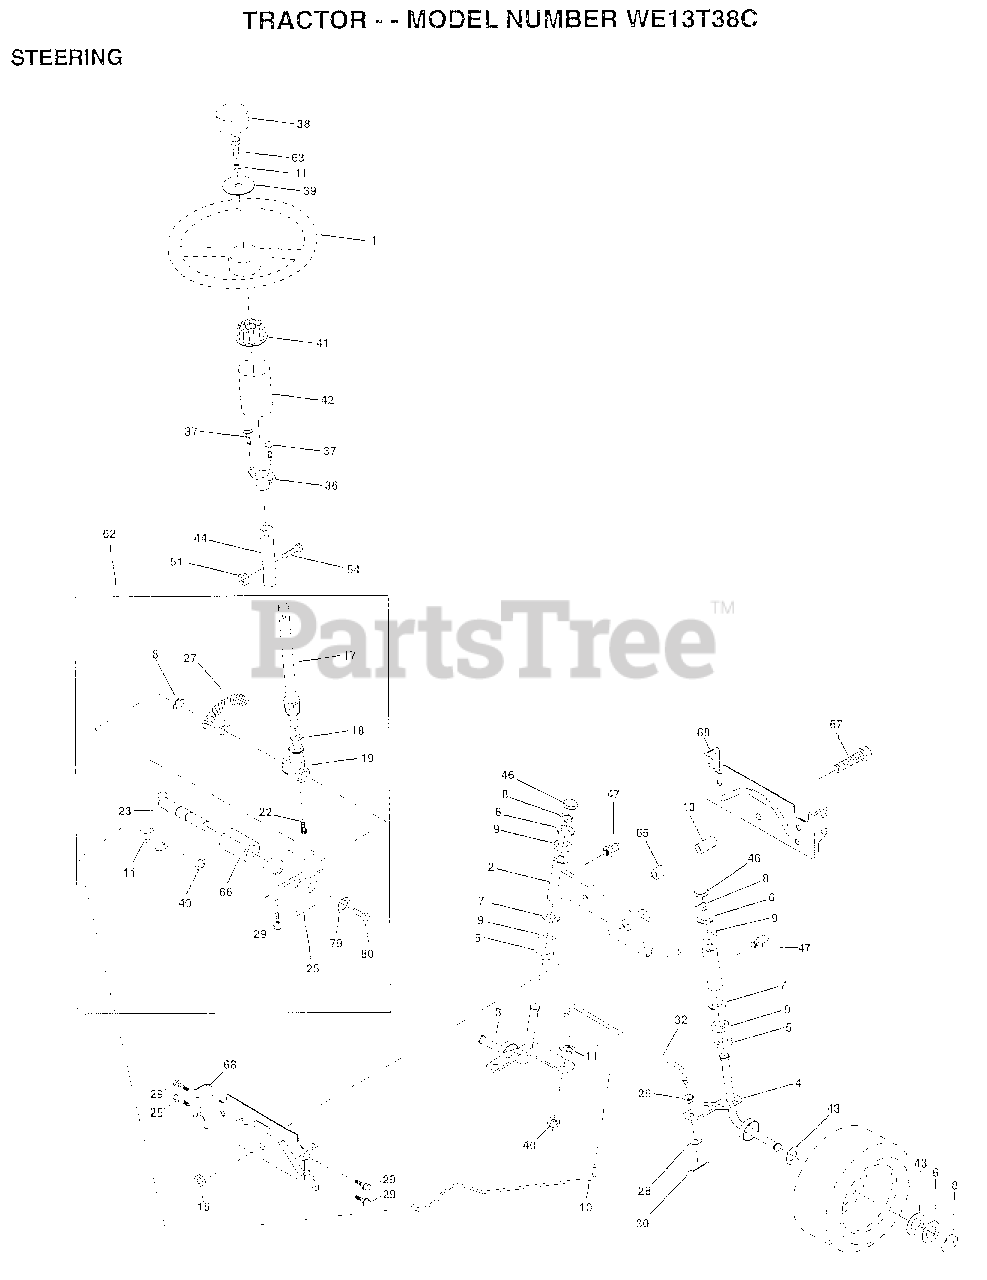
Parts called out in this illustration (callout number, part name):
1	WHEEL STR AYP BLK
2	AXLE ASM
3	SPINDLE.ASM.LH
4	"SPINDLE ASM,RH"
5	WASHER .T
6	WASHER
7	WASHER
8	RING
9	COL. SRTG. BEAR.
10	DRAGLINK-STAMPED
11	LOCKWASHER
13	BEARING AXLE
15	"NUT-LOC,FLANGE LT"
17	SHAFT ASM STEERIN
18	THRUST WASHER
19	SUPPORT.SHAFT.STEER
22	SCREW.HX.WSH.HD
23	SHAFT.ASM.PITMAN
25	BRKT-STEERING
26	BUSHING.DRAGLINK
27	GEAR SECTOR
28	WASHER
29	SCREW
30	COTTER PIN
32	TIE ROD
36	BUSHING.STEERING
37	"SCREW-TT,10-32 FL"
38	CAP STEER AYP
39	WASHER T
40	GRIPCO NUT
41	ADAPTER LT
42	BOOT.STEER.PL
43	WASHER
44	EXT SHAFT STEERIN
46	CAP
47	ZERK M
51	NUT
54	BOLT
62	KIT.STEER.ASM
63	BOLT
65	SPACER AXLE
66	"BEARING-ARM,PITMA"
67	BOLT
68	BRACE AXLE
79	WASHER
80	BOLT.HX.NYLON3/8-16X3/
